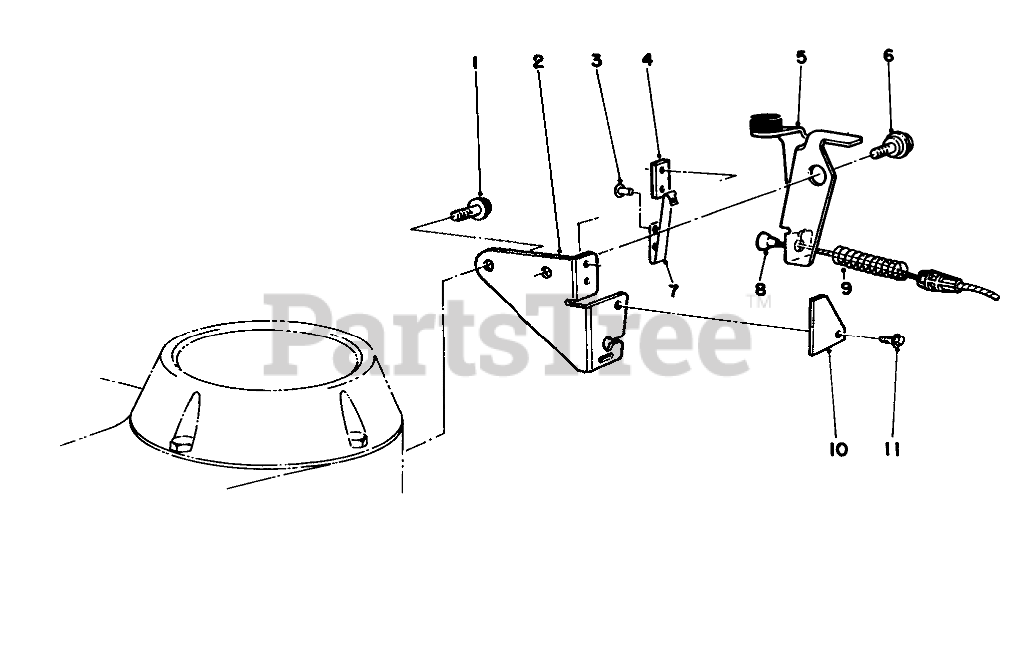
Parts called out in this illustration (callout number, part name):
1	THO FORM SCREW M6 X 1
2	PLATE-BRAKE
3	RIVET-PLASTIC
4	STRAP-INSULATING
5	BRAKE PLATE ASM
6	Screw-Shoulder
7	STRAP-GROUND
8	BRAKE CABLE
9	SPRING-COMPRESSION
10	STOP-GROUND STRAP
11	SCREW-HWH
